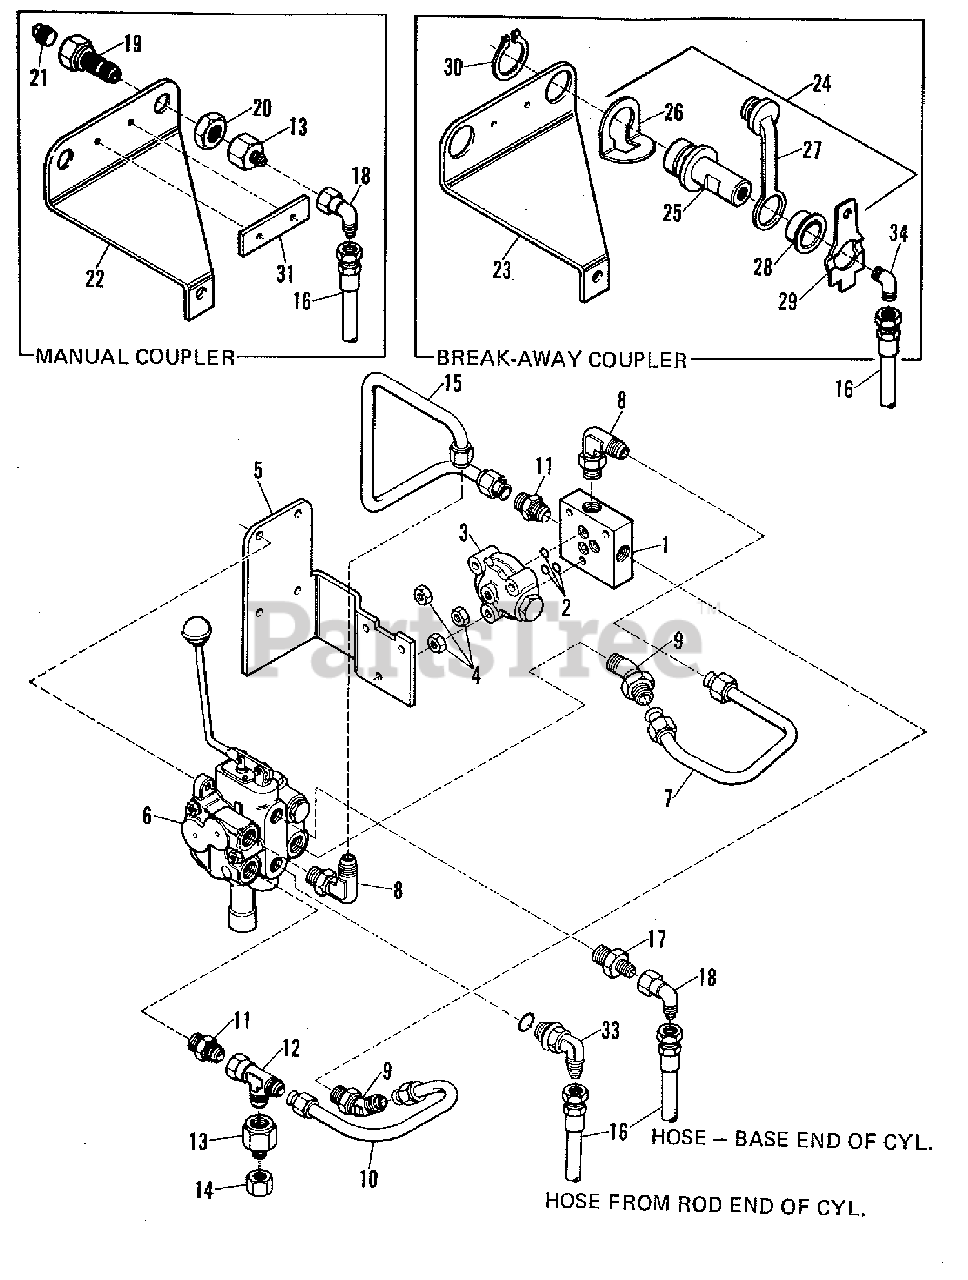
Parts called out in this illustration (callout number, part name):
1	MANIFOLD
1	CAPSCREW, M8 x 1-1/4 x 70MM
1	LOCKWASHER, M8
3	COVER ASSEMBLY
5	BRACKET, Valve Mounting
5	CAPSCREW, M8 x 90, Gr. 8.8
5	CAPSCREW, M8 x 85, Gr. 8.8
5	LOCKWASHER, M8
6	VALVE ASSEMBLY, Remote
6	CAPSCREW, 3/8NC x 1-1/4
6	LOCKWASHER, 3/8
7	TUBE ASSEMBLY (Manifold to Valve Inlet)
8	ELBOW, 90 Degrees (w/O-Ring)
9	ELBOW, 45 Degrees (w/O-Ring)
10	TUBE ASSEMBLY (Valve Outlet to Manifold)
11	CONNECTOR, Short (w/O-Ring)
13	REDUCER, Tube
15	TUBE ASSEMBLY (Valve Outlet to Manifold)
16	HOSE, Remote
17	CONNECTOR, Reducer (w/O-Ring)
18	ELBOW, Swivel Nut
22	BRACKET, Mounting (For Manual Coupler)
23	BRACKET, Mounting (For Breakaway Coupler)
24	COUPLER ASSEMBLY
27	COVER, Dust
29	HANDLE, Release
31	CAPSCREW, 1/4NC x 3/4
31	LOCKWASHER, 1/4
32	SEAL KIT, Coupling
33	ELBOW, Adjustable (w/O-Ring)
